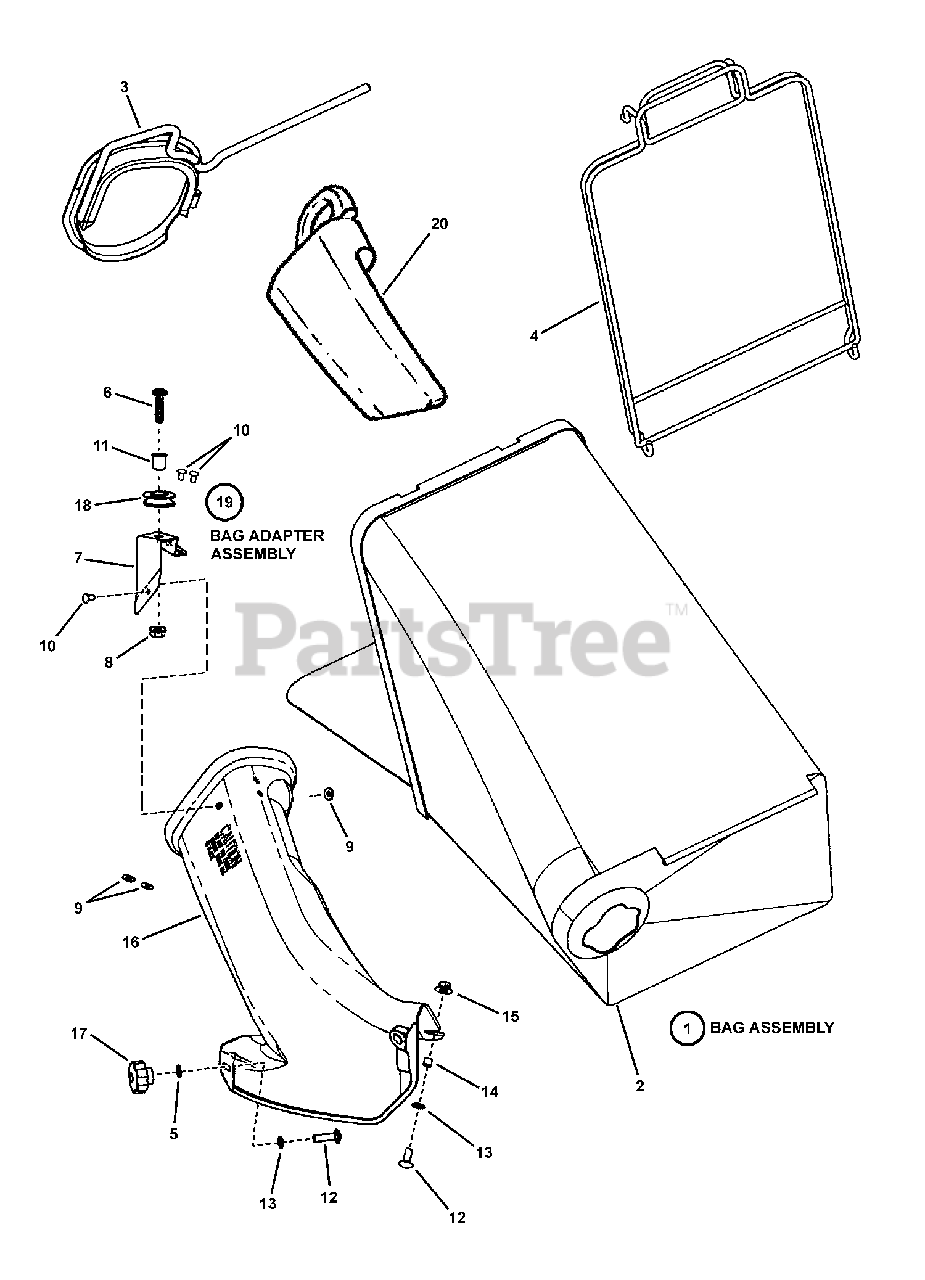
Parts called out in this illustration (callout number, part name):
1	BAG ASSEMBLY, (Door)
2	GRASS BAG, (Door) No Graphics
3	CONNECTOR, Grass Bag (weldment)
4	ASSEMBLY, Bag Wire (12" Wide)
5	WASHER, 5/16" Internal/External Tooth Lock
6	SCREW, 5/16-18 x 1-1/4" Hex Head Cap
7	BRACKET, Rope Guide
8	NUT, 5/16-18 Hex Flange Lock, GR 5
9	WASHER, 15/32" Flat
10	RIVET, 3/16 x .344
11	BUSHING, Flange, .381 x .625 x .62
12	BOLT, 5/16-18 x 3/4" Short Neck Carriage GR 5
13	RETAINER, 5/16" Bolt
14	SPACER, .316 I.D. x .375 O.D. x .310 thick
15	NUT, 5/16-18 Hex Large Flange Center Lock
16	ADAPTER, Grass Bag
17	KNOB, Fluted, 5/16-18 x 1/2"
18	PULLEY, Nylon
19	ASSY, Grass Bag Adapter
20	PLUG, Chute Adapter
